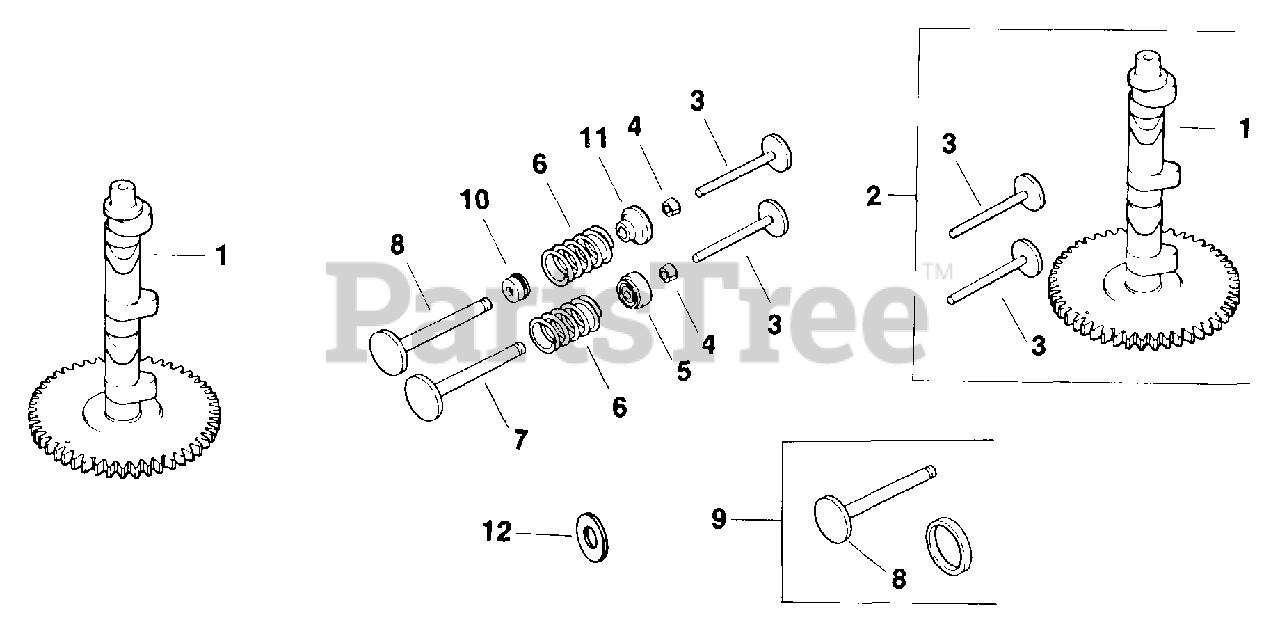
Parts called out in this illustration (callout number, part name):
1	CAMSHAFT-DISCONTINUED
2	KIT, CAMSHAFT - DISCONTINUED
3	TAPPET
4	KIT, RETAINER
7	VALVE, EXHAUST
8	VALVE - DISCONTINUED
9	KIT, VALVE - (#DSC)
11	RETAINER, VALVE SPRING
